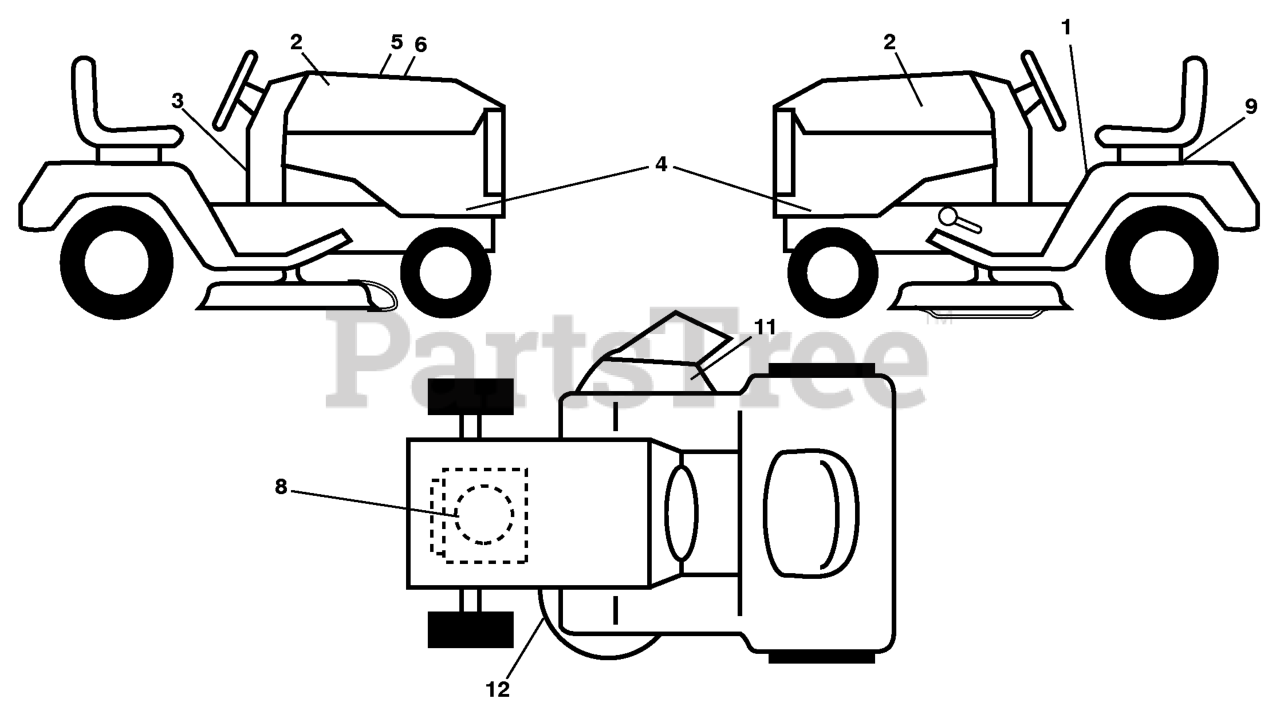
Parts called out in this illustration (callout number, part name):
1	DECAL.FENDER.WARNING.ENG
2	DECAL.HOOD.LOGO.ORANGE.HUSQVAR
3	DECAL, WARNING SPARK ARRESTOR
4	DECAL PANEL SIDE
5	DECAL.WARNING.CUST.RESP.E85.
6	Decal, Replacement
8	DECAL.ENG.BS.20HPXRD.SL.278416
9	DECAL BTRY SYMBOLS
11	DECAL.WARN.KEEP.HAND.AWAY
12	DECAL V BELT SCHEMATIC
